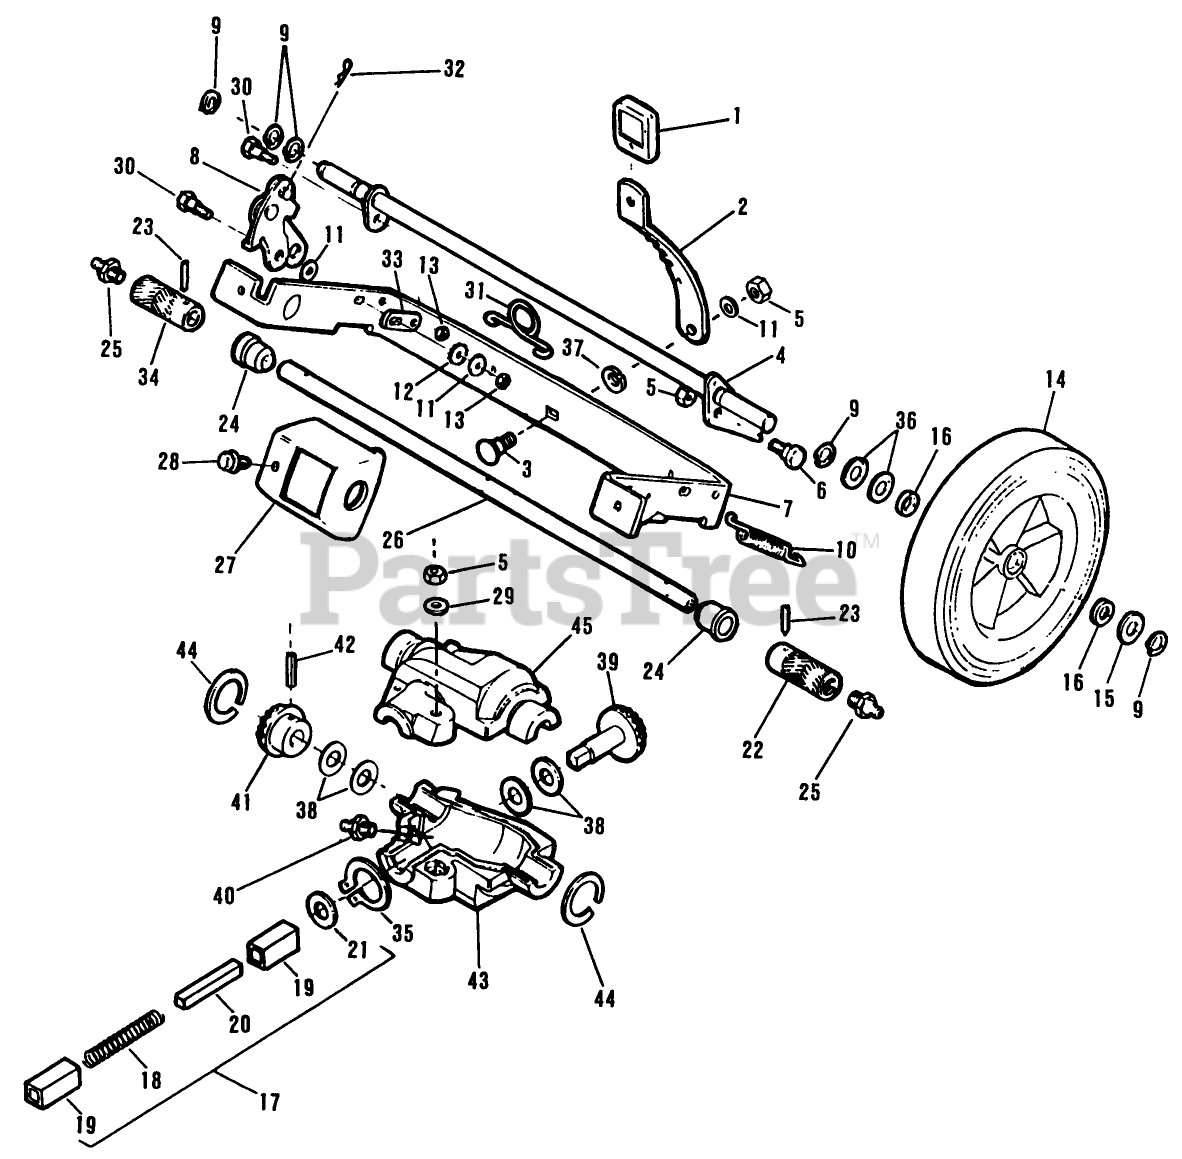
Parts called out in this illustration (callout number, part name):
2	LEVER
5	LOCKNUT E
6	BOLT RB&W
7	BRACKET *GREEN
8	CLUTCH AY ARGO
9	RET RING
10	SPRING
11	WASHER S
13	STOP NUT
14	WHEEL & TIRE KIT
15	SPACER
16	WASHER
18	SPRING
19	BUSHING BKWY
21	THRUST WASHER
22	ROLLER (LEFT) VS
22	ROLLER-LH
23	PIN GROOVE TB&S
24	SLEEVE &BEARING AY
25	GREASE FITTING AP
26	DRIVE SHFT TAG AY
29	WASHER F
30	BOLT RB&W
31	SPRING N.A.S
34	ROLLER (RIGHT) VS
34	ROLLER-RH
36	SPACER
37	WASHER SPRING LAR
38	THRUST WASHER
39	GEAR BEST
40	ZERK FITTING
41	GEAR ADVANCE
42	ROLL PIN
